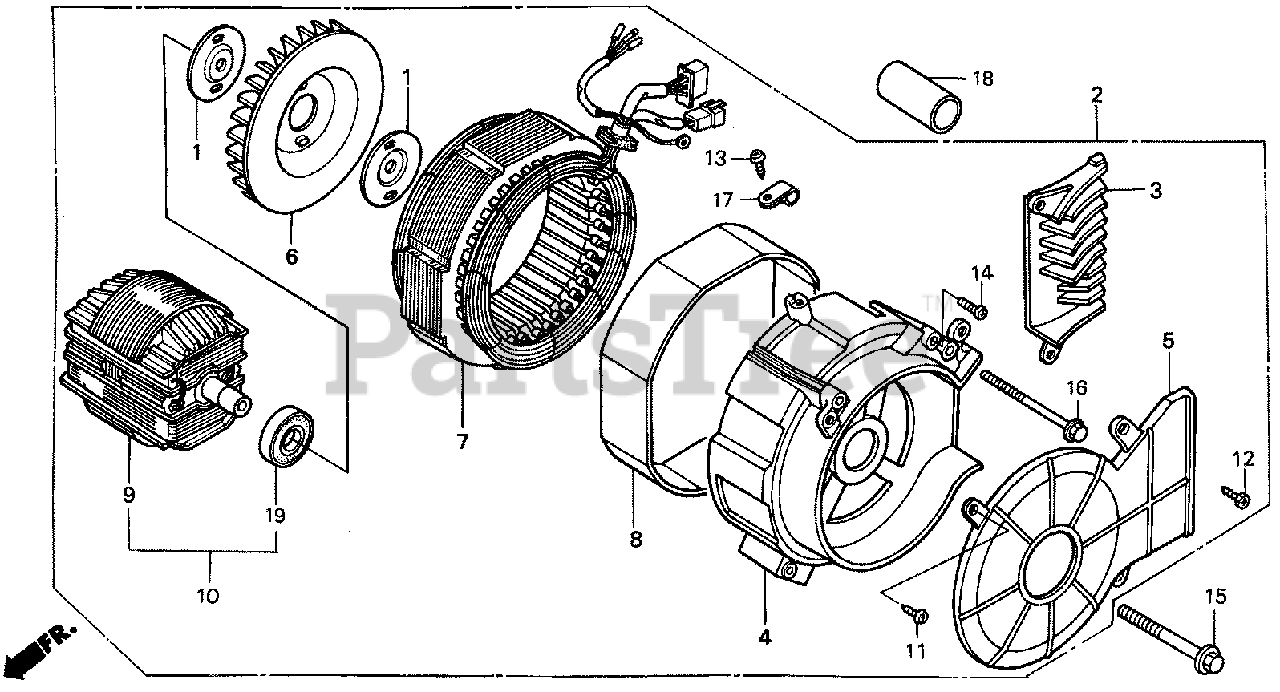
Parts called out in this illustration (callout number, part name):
1	PLATE, FAN SETTING
2	GENERATOR ASSY. (EX-A)
3	GUIDE, GENERATOR AIR
4	HOUSING, RR.
5	COVER, GENERATOR FAN
6	FAN, COOLING
7	STATOR ASSY. (EX-A)
8	COVER, STATOR
11	SCREW, TAPPING (5X14)
12	SCREW, TAPPING (5X18)
13	SCREW, TAPPING (5X12)
14	SCREW, PAN (5X12)
15	BOLT, FLANGE (8X110)
16	BOLT, FLANGE (6X150)
17	CLIP (9MM)
18	TUBE, CORD
19	BEARING ASSY. (6002)
